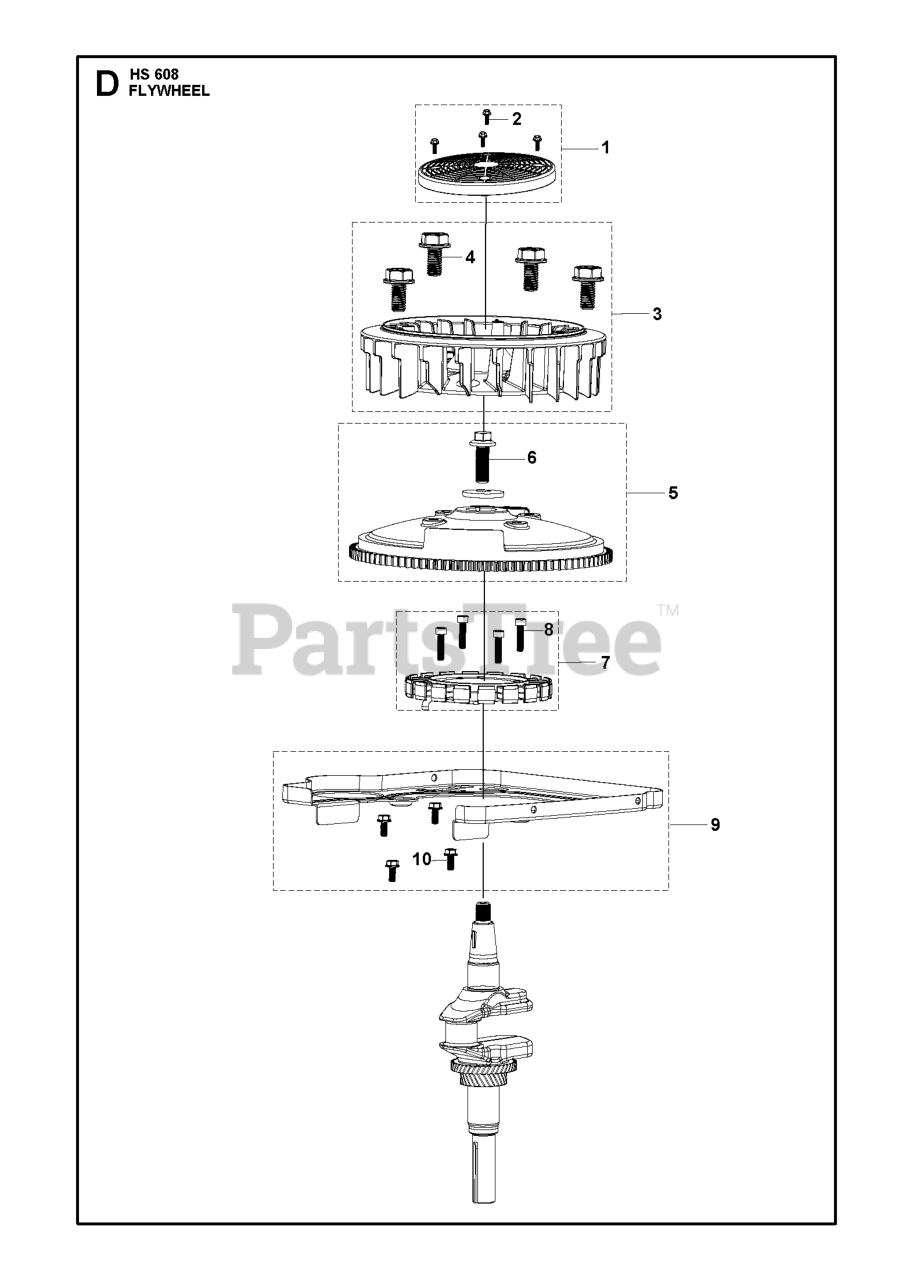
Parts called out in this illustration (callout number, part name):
1	COVER KIT COVER IMPELLER
2	Husqvarna TBD
7	ARMATURE ARMATURE
9	PLATE SIDE PLATE
